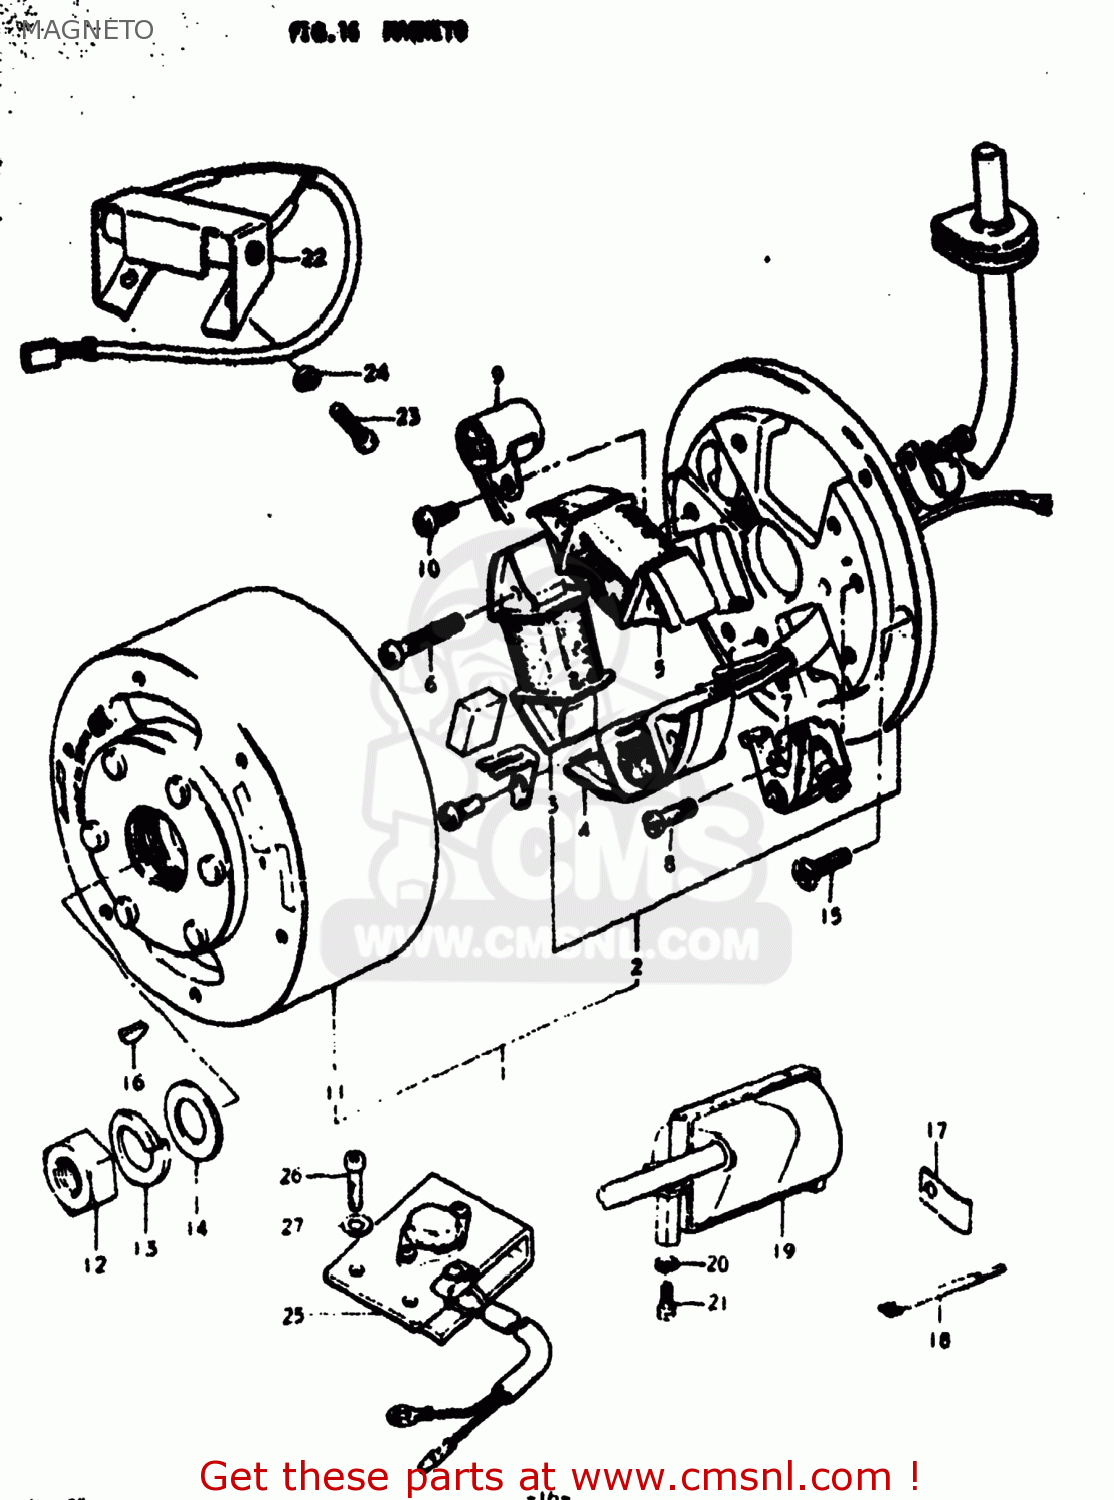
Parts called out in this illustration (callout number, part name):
1	MAGNETO ASSEMBLY
2	STATOR ASSEMBLY
3	COIL,LIGHTING
4	COIL,LIGHTING
5	COIL,PRIMARY
6	SCREW
7	POINT ASSEMBLY,CONTACT
8	.SCREW
9	CONDENSER
10	SCREW
11	ROTOR ASSEMBLY
12	NUT (10MM)
13	LOCK WASHER
14	WASHER
15	SCREW
16	KEY
17	CLAMP L:35
18	CLAMP
19	COIL ASSEMBLY,IGNITION
20	LOCK WASHER
21	BOLT
22	REGISTER ASSEMBLY,SAFETY L
23	SCREW
24	LOCK WASHER
25	REGULATOR ASSEMBLY
26	SCREW 6X12
27	WASHER
